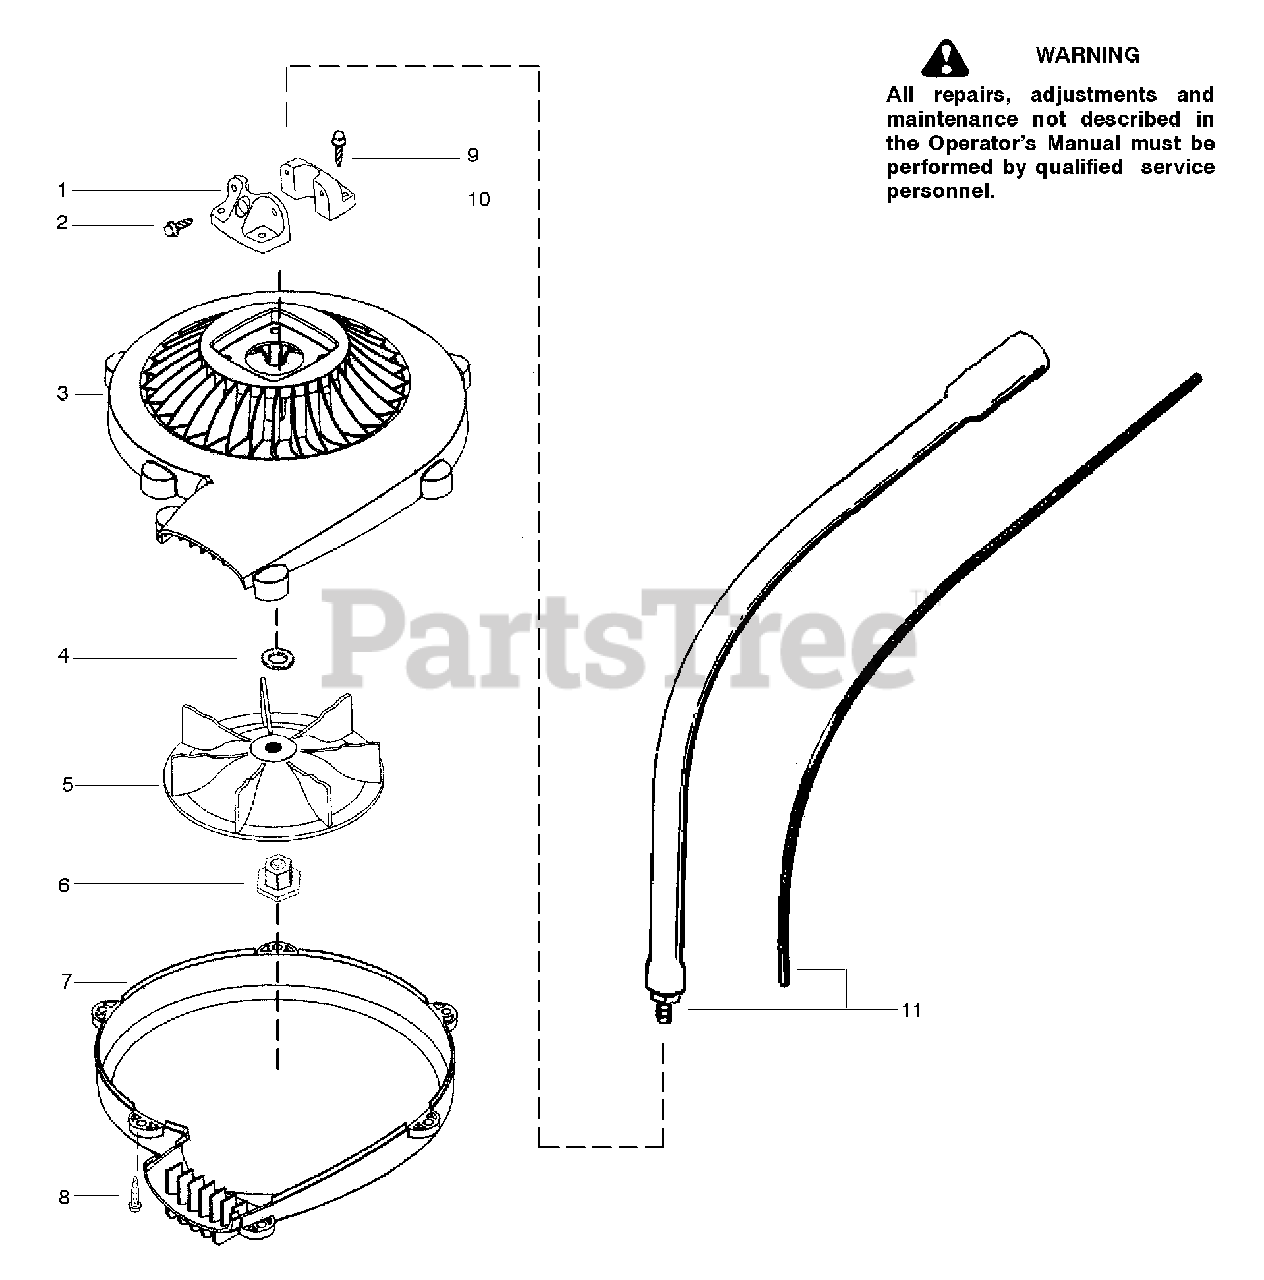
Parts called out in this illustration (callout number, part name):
1	Clamp-Right
3	Hsg.-Blower
5	Impeller
6	Arbor-Impeller
7	Hsg.-Blower
10	Clamp-Left
11	Kit-Lower Driveshaft
